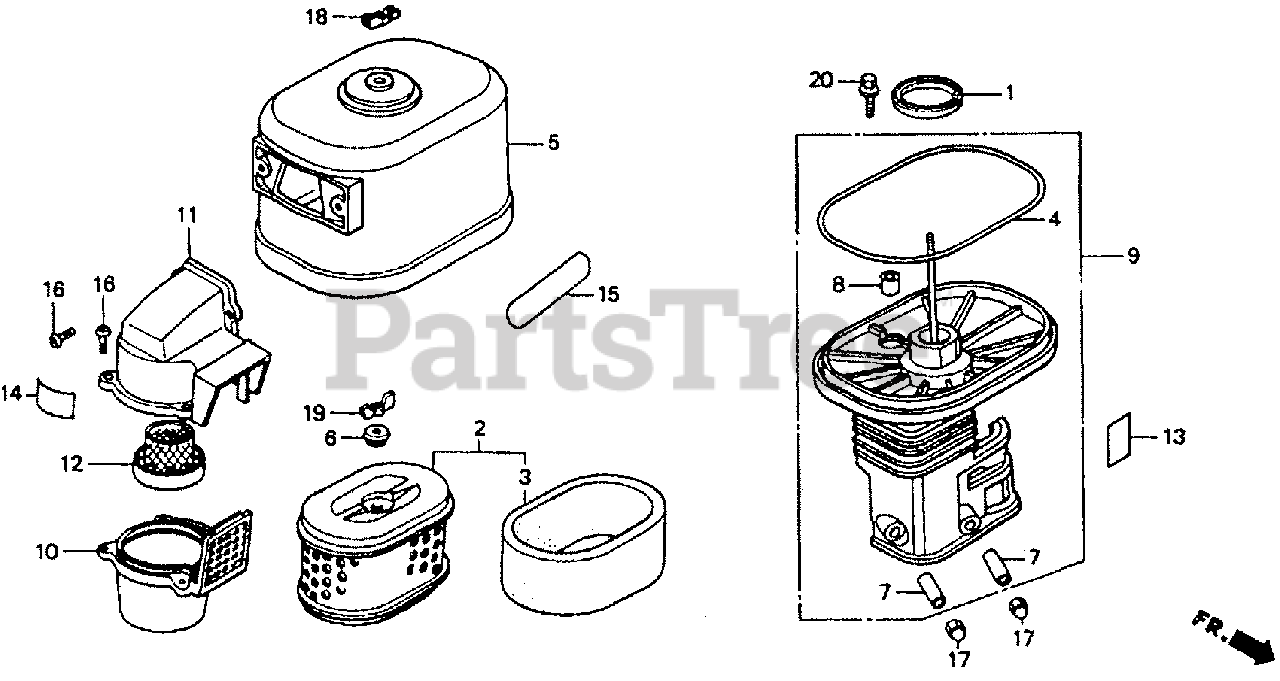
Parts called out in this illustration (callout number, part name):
1	GASKET, ELBOW
2	ELEMENT, AIR CLEANER
3	FILTER (OUTER)
4	SEAL, AIR CLEANER COVER
5	COVER, AIR CLEANER (CYCLONE)
6	GROMMET, AIR CLEANER
7	COLLAR, AIR CLEANER
8	COLLAR B, AIR CLEANER
9	ELBOW, AIR CLEANER
10	CASE, PRE AIR CLEANER
11	CAP, PRE AIR CLEANER
12	GUIDE, PRE AIR CLEANER
13	MARK, CHOKE (EXTERNAL)
14	LABEL, AIR CLEANER CAUTION
15	MARK, AIR CLEANER SALES POINT
16	SCREW, PAN (5X16.5)
17	NUT, CAP (6MM)
18	WINGNUT, AIR CLEANER COVER
19	WINGNUT, TOOL BOX SETTING
20	BOLT-WASHER (6X20)
